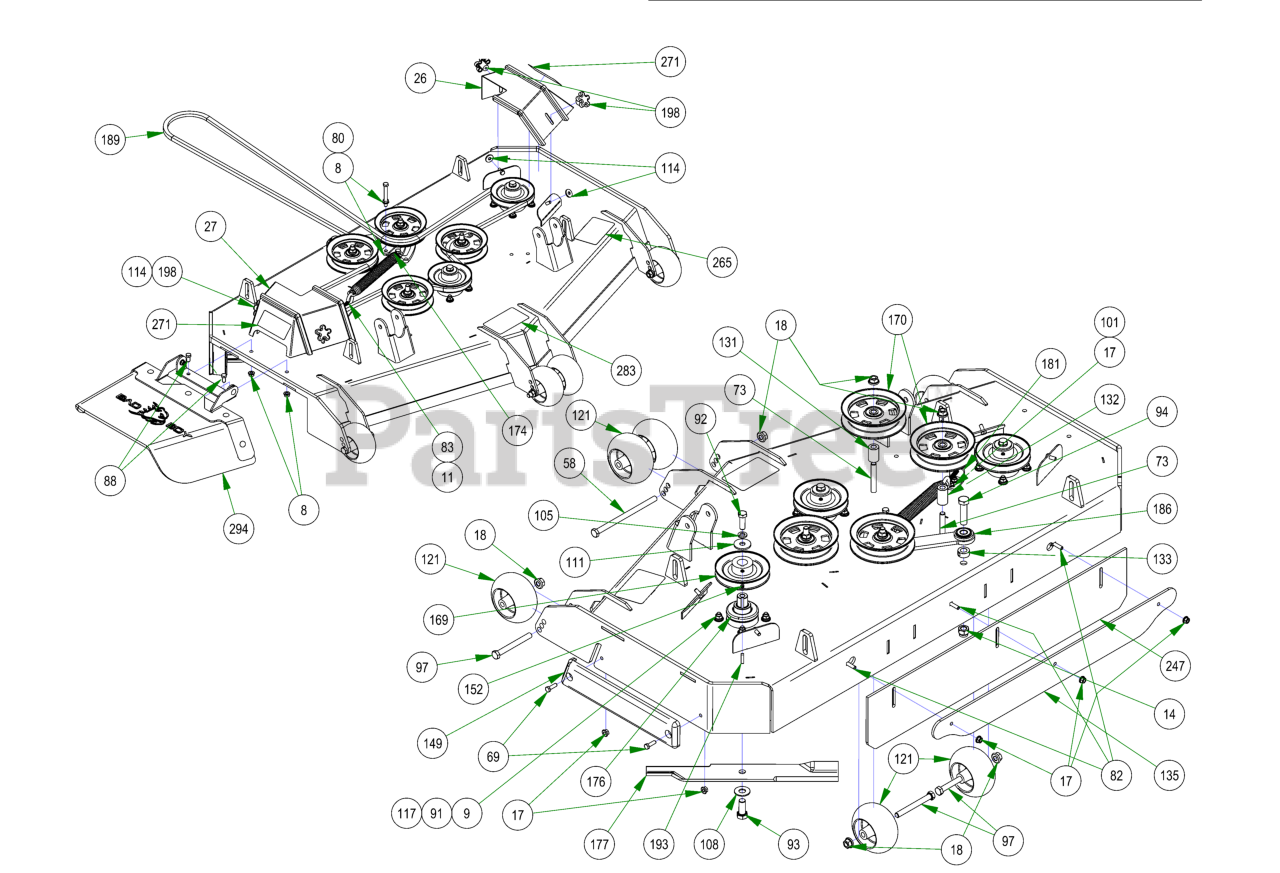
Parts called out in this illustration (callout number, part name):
8	3/8-16 HEX SERRATED FLANGE NUT HARD/ZINC
9	3/8-16 NYLON INSERT FLANGE LOCKNUT (GR.F) ZINC
11	3/8-16 HEX NUT ZINC
14	5/8-11 NYLON INSERT LOCKNUT ZINC
17	5/16-18 NYLON INSERT FLANGE LOCKNUT ZINC
18	1/2-13 NYLON INSERT FLANGE LOCKNUT ZINC
26	2019 54" Left Outlaw Gen2 Pulley Cover
27	2019 54" Right Outlaw Gen2 Pulley Cover
58	1/2-13 X 8 HEX CAP SCREW GR 5 ZINC
69	5/16-18 X 1 HEX CAP SCREW (GR.5) ZINC
73	1/2-13 X 3-1/2 HEX FLANGE BOLT (GR.8) ZINC
80	3/8-16 X 3 HEX CAP SCREW (GR.5) ZINC
82	5/16-18 X 1-1/4 CARRIAGE BOLT ZINC
83	4" 3/8-16 Eye Bolt
88	3/8-16 X 3/4 HEX CAP SCREW (GR.5) ZINC
91	3/8-16 X 1-1/2 HEX CAP SCREW (GR.5) ZINC
92	1/2-20 X 1-1/2 HEX CAP SCREW (GR.5) ZINC
93	5/8-18 X 1-1/2 HEX CAP SCREW (GR.8) ZINC YELLOW
94	5/8-11 X 2-1/2 HEX CAP SCREW (GR.5) ZINC
97	1/2-13 X 4-1/2 HEX CAP SCREW (GR.5) ZINC
101	5/16-18 X 7/8 CARRIAGE BOLT ZINC
105	1/2 SPLIT LOCKWASHER (GR.8) ZINC/YELLOW
108	5/8 USS FLAT WASHER (1-3/4" OD) GR.8 ZINC YELLOW
111	1/2 BELLEVILLE WASHER (1-5/8 OD X .140 THK) ZINC
114	.360 ID X .983 OD X .120 THICK FLAT WASHER NYLON
117	5/16 USS FLAT WASHER (7/8 OD) ZINC
121	2019 Deck Wheel
131	.502 ID X .750 OD X 1.500 Long Spacer
132	1 3/4" Pulley Spacer
133	5/8 SOLID SHAFT COLLAR (W/1 SET SCREW) ZINC
135	61 Bolt in Baffle Deck v2 Stripping Plate
149	REVISED TRIM BUMPER_20180226
152	5/16-24 X 1/4 SOCKET SET SCREW (CUP PT) PLAIN
169	5.25" Deck Spindle Pulley
170	5-3/4 Idler Pulley
174	2019 Outlaw Gen2 Deck Spring
176	OUTLAW SPINDLE ASSEMBLY
177	54" Fusion Blade for ZT/Mav/Outlaw/Revolt
181	2019 Deck Eye Bolt Tab
186	2019 Rebel Rogue Deck Idler
189	B165 Belt-60 54" deck Outlaw
193	1/4 X 1 SQ MACHINERY KEY 1018 STL PLN
198	5/16" Knob
218	2019 Sloped 54" Deck
247	R Series Rubber For Deck
265	2018 54" Deck Decal
271	Danger Decal-Spindle/Discharge
283	2019 Rebel & Rogue Deck Belt Route Decal
294	2019 Outlaw Gen2 Chute Assembly
